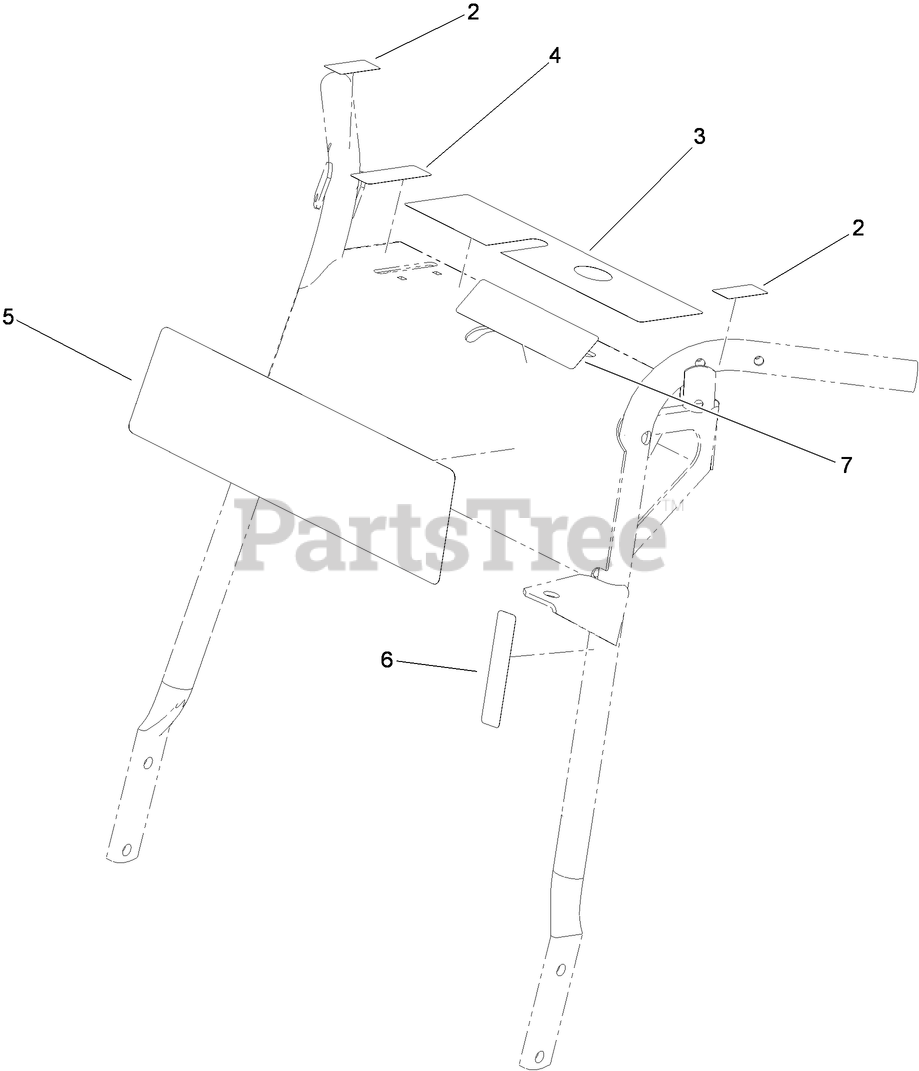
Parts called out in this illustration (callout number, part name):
2	DECAL-LOCK,NEUTRAL
3	DECAL-PANEL, CONTROL
4	DECAL-THROTTLE
6	DECAL-ENGAGE, DECK
7	DECAL - SLOPE, INT'L
